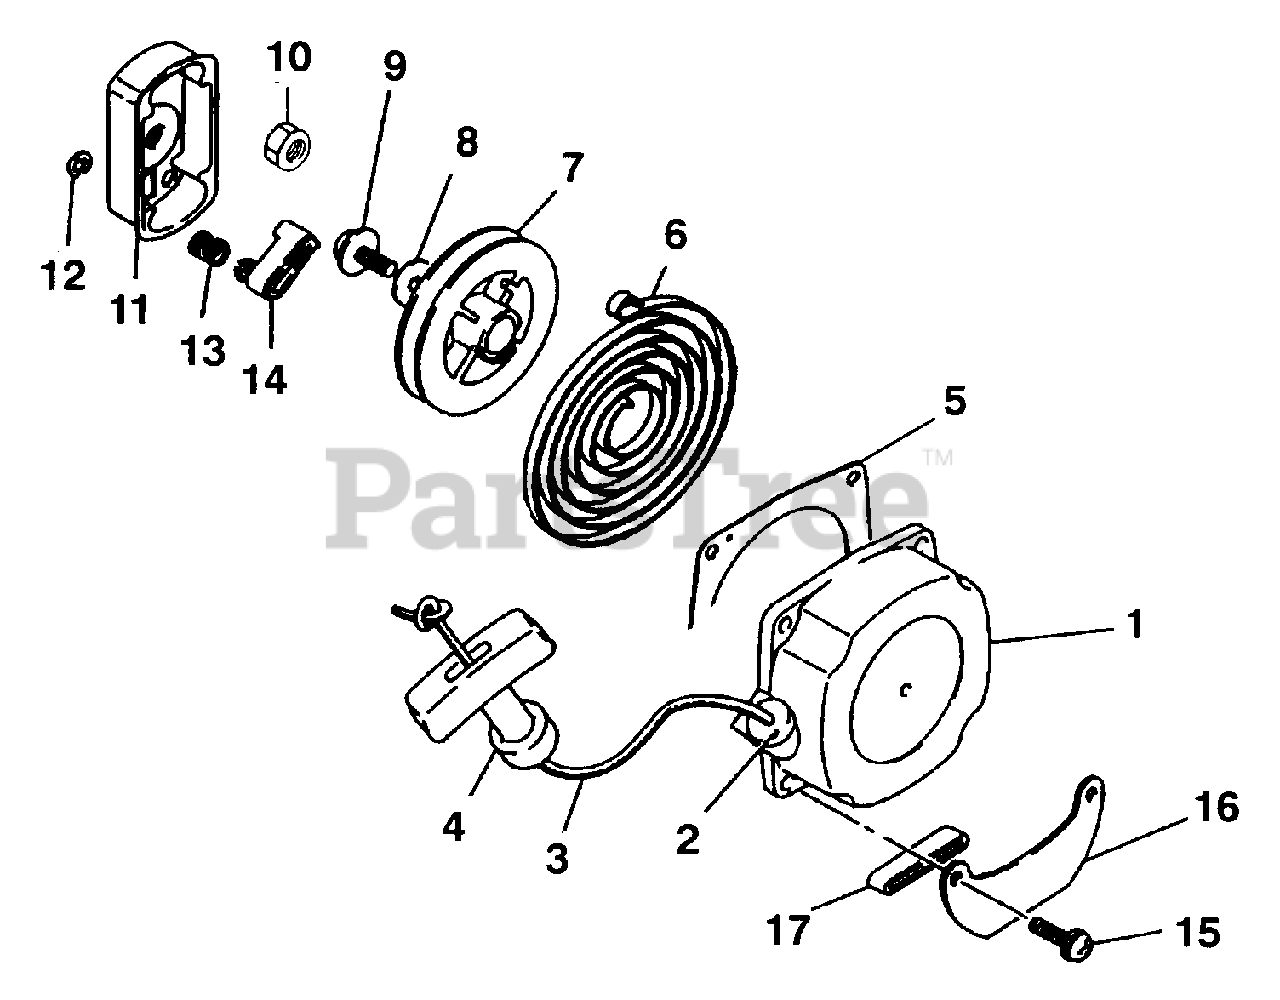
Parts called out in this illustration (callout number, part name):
1	Starter Assembly
9	Screw & Washer
10	Nut
11	Pulley Assembly
12	Snap Ring
13	Spring, Return
15	Screw & Washer
17	Pad, Bracket
